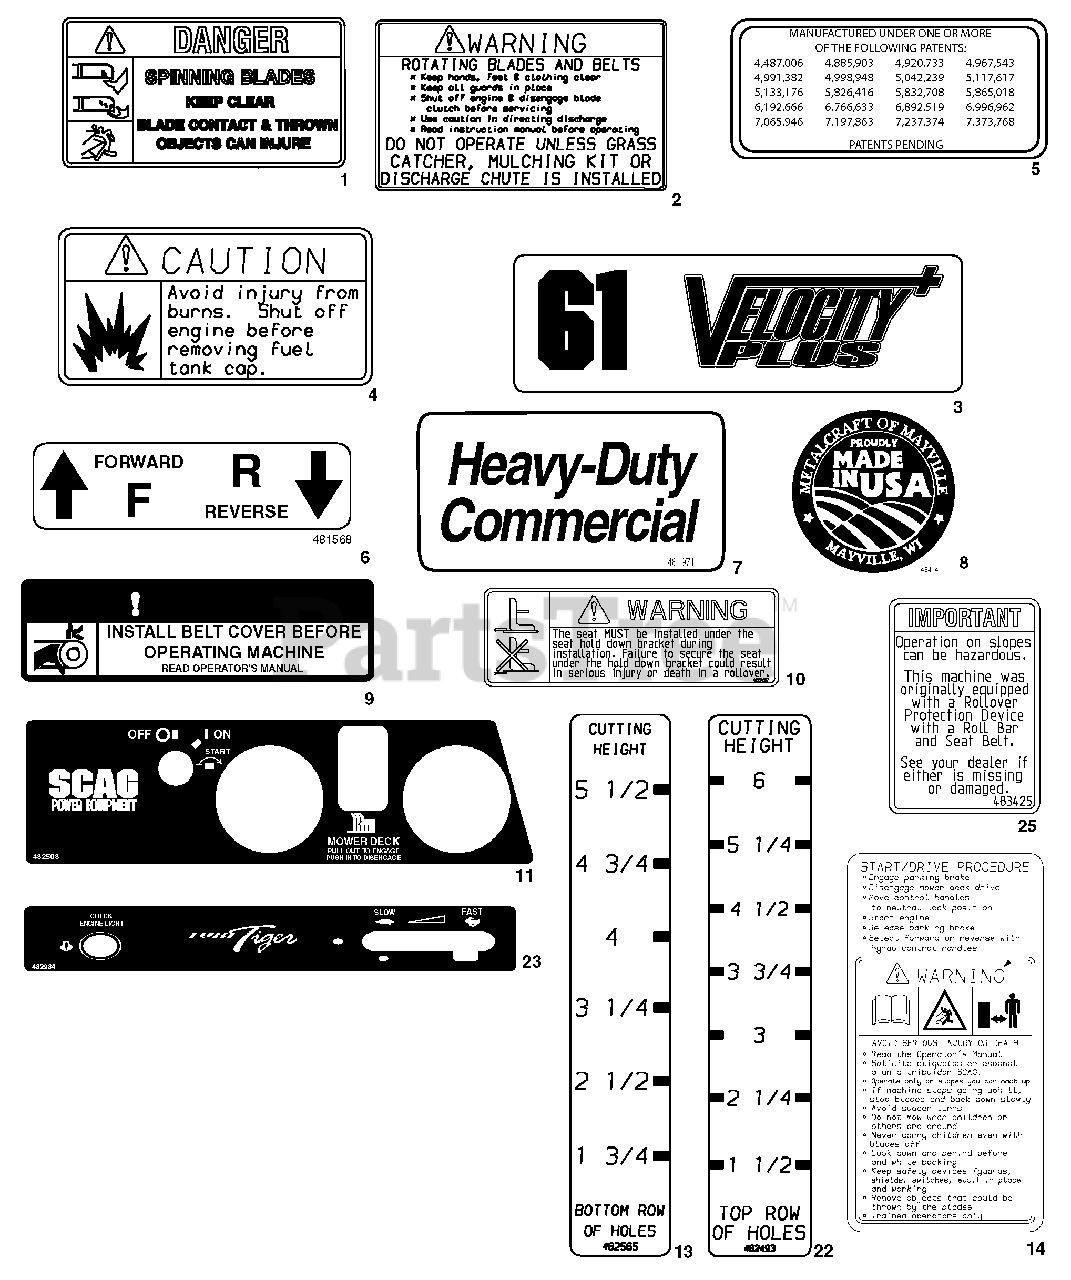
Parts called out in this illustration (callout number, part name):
1	Decal, Danger-Spinning Blades
2	Decal, Warning-Rotating Blades
3	Decal, 61 Velocity Plus
3	Decal, 72 Velocity Plus
4	Decal, Fuel Tank
5	Decal, Patents
6	Decal, Traction Control
7	Decal, Heavy Duty Commercial
8	Decal, Metalcraft-Made In USA
9	Decal, Belt Cover
10	Decal, Warning Seat Hold Down
11	Decal, Instrument Panel-Upper
13	Decal, Cutting Height - Lower
14	Decal, Start/Drive Procedure
23	Decal, Instrument Panel - Lower
25	Decal, ROPS
